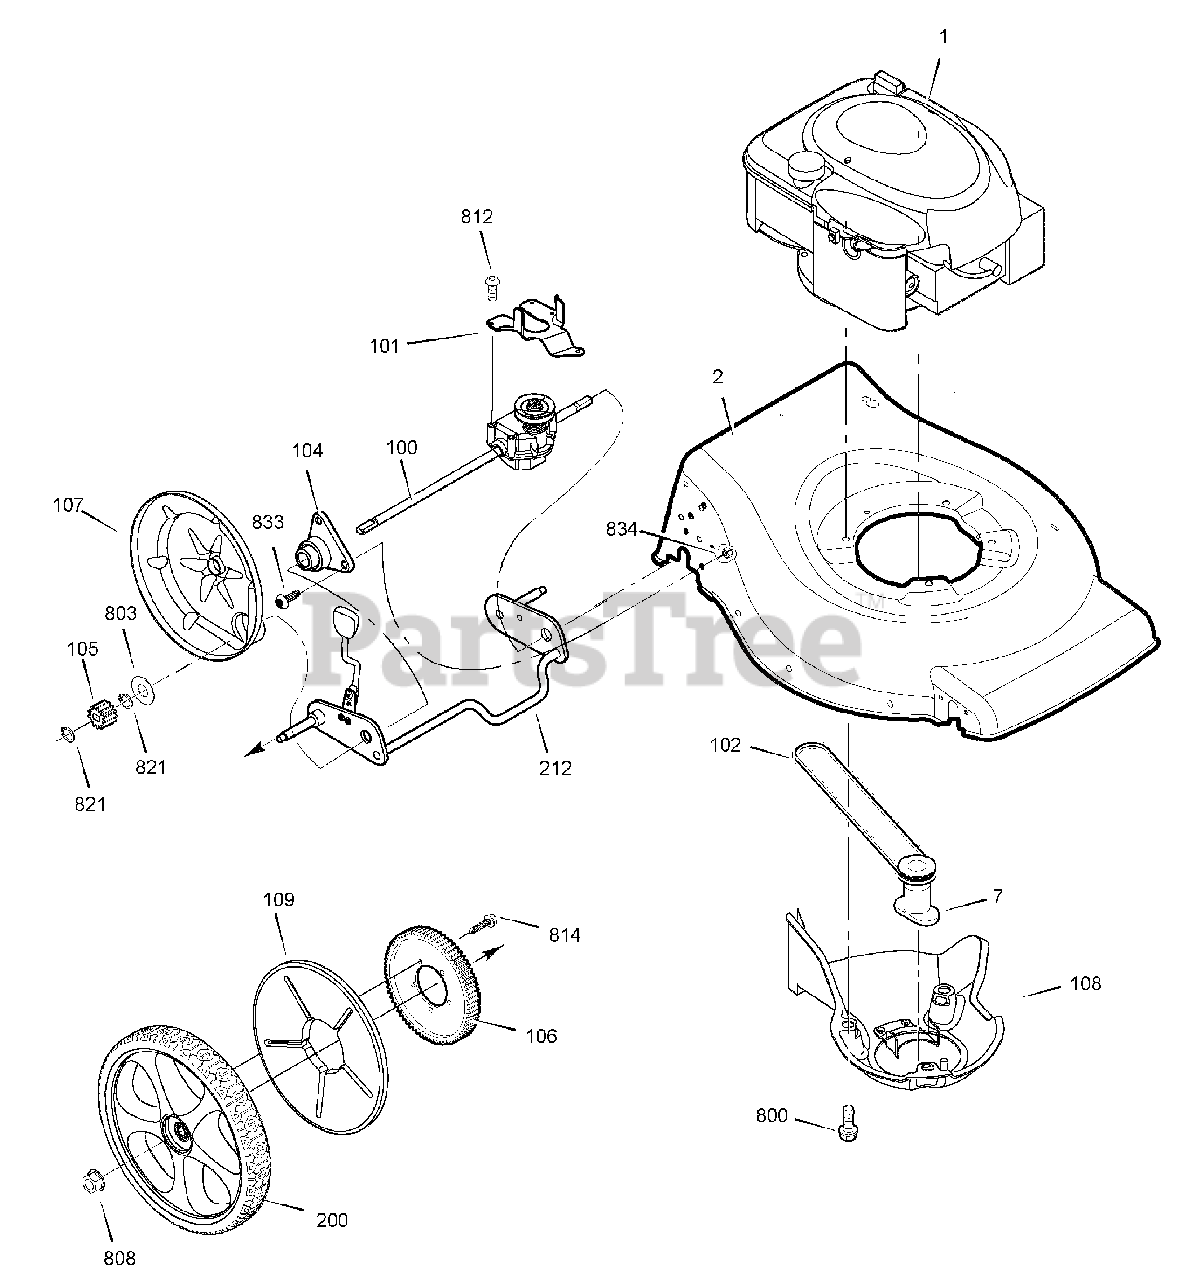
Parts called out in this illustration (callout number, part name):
1	*ENGINE
2	MOWER HOUSING
7	BLADE ADAPTER ASSEMBLY
100	TRANSMISSION
101	BELT GUIDE, Transmission
102	V-BELT
104	SLEEVE ASSEMBLY, Rear Axle
105	GEAR, Pinion
106	GEAR, Drive
107	DUST COVER
108	BELT COVER ASSEMBLY
109	COVER, Wheel
200	WHEEL, Rear
212	CROSSBAR ASSEMBLY, Rear
800	SCREW, Hex Head, 3/8-16 x 1
803	WASHER, Thrust
808	NUT, Flange, 3/8-16
812	SCREW, #10 x 1
814	SCREW, 1/4-15 x 3/4
821	RING, External Retaining
833	SCREW, Torx, 1/4-20 x 5/8
834	NUT, Flange Lock, 1/4-20
